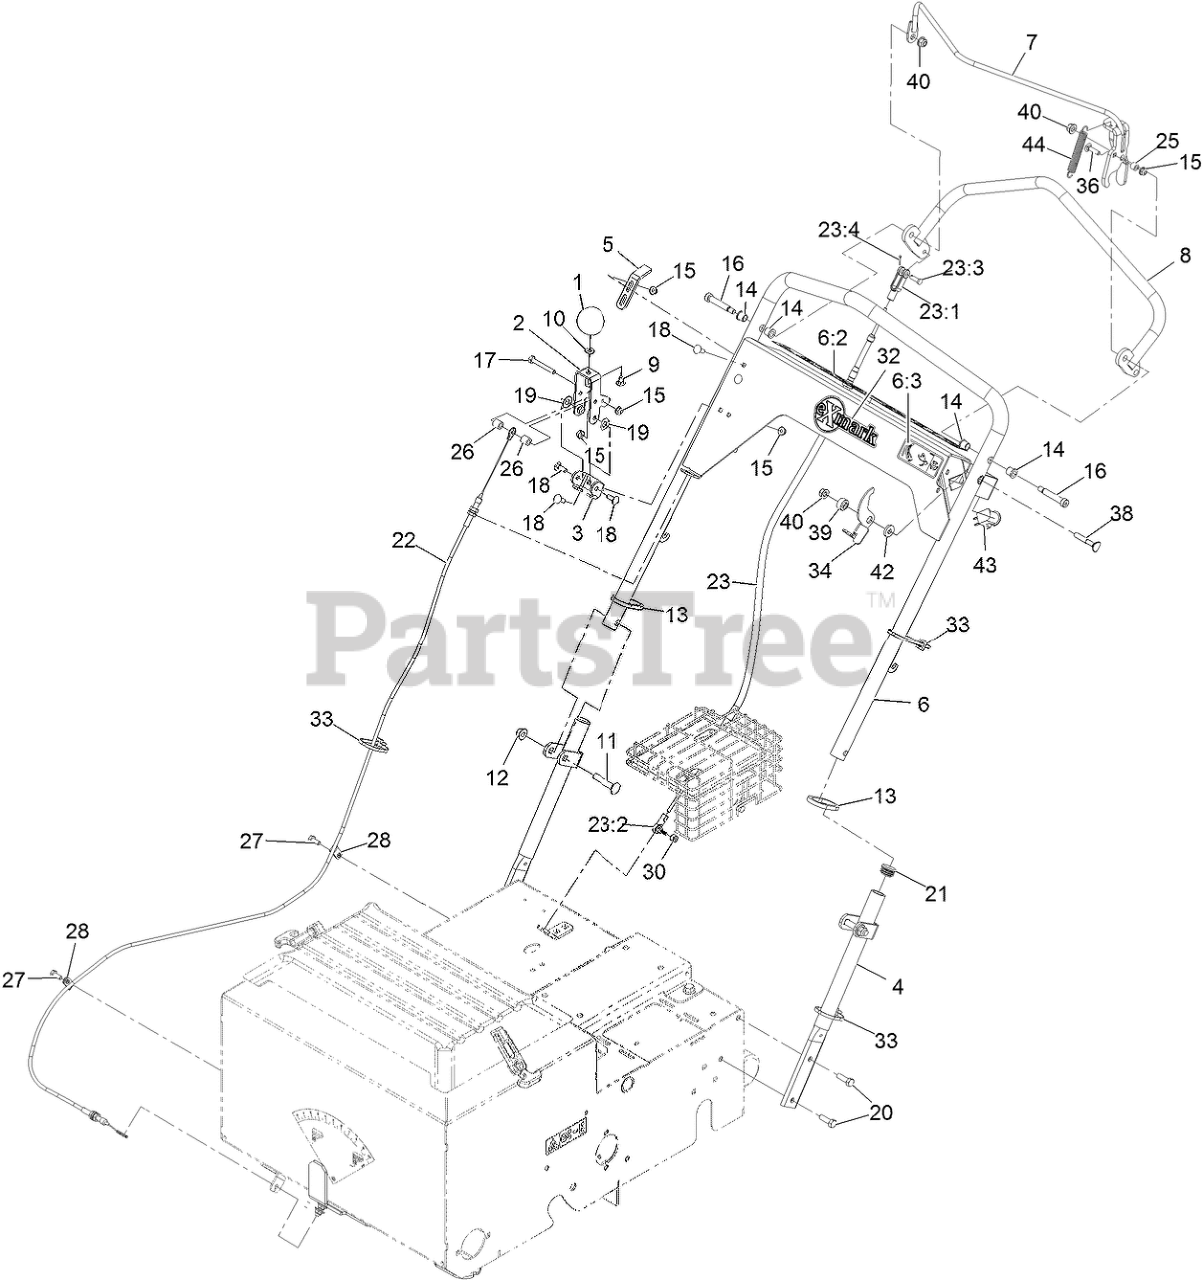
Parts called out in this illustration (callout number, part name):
1	KNOB-RATE, FLOW
2	LEVER-ADJUST, FLOW
3	BRACKET-ADJUST, FLOW
4	HANDLE-LOWER
5	BRACKET-ADJUST, DRIVE
6:2	DECAL-CONTROL PANEL, SEED
6:3	DECAL-SAFETY LATCH
7	BAIL-CLUTCH
8	HANDLE-DRIVE
9	SCREW-CARR
10	WASHER-FLAT
11	SCREW-CARR
12	NUT-HF, NI
13	RING-HANDLE LOCK
14	BEARING
16	SCREW-SHOULDER
17	SCREW-HH
18	BOLT-CARR
19	WASHER-PLAIN
20	SCREW-HH
22	CABLE-FLOW, SEED
23	CABLE-PUSH PULL
23:2	Ball Joint
23:3	Pin-Clevis
23:4	PIN-COTTER
27	SCREW-HH
28	CLAMP-R
30	NUT-LOCK
32	DECAL-EXMARK LOGO
33	TIE-CABLE
34	LATCH-BAIL
36	SCREW-CARR
39	BUSHING-STEPPED
40	NUT-HF, NI
42	WASHER-FLAT
43	SWITCH-BAIL
